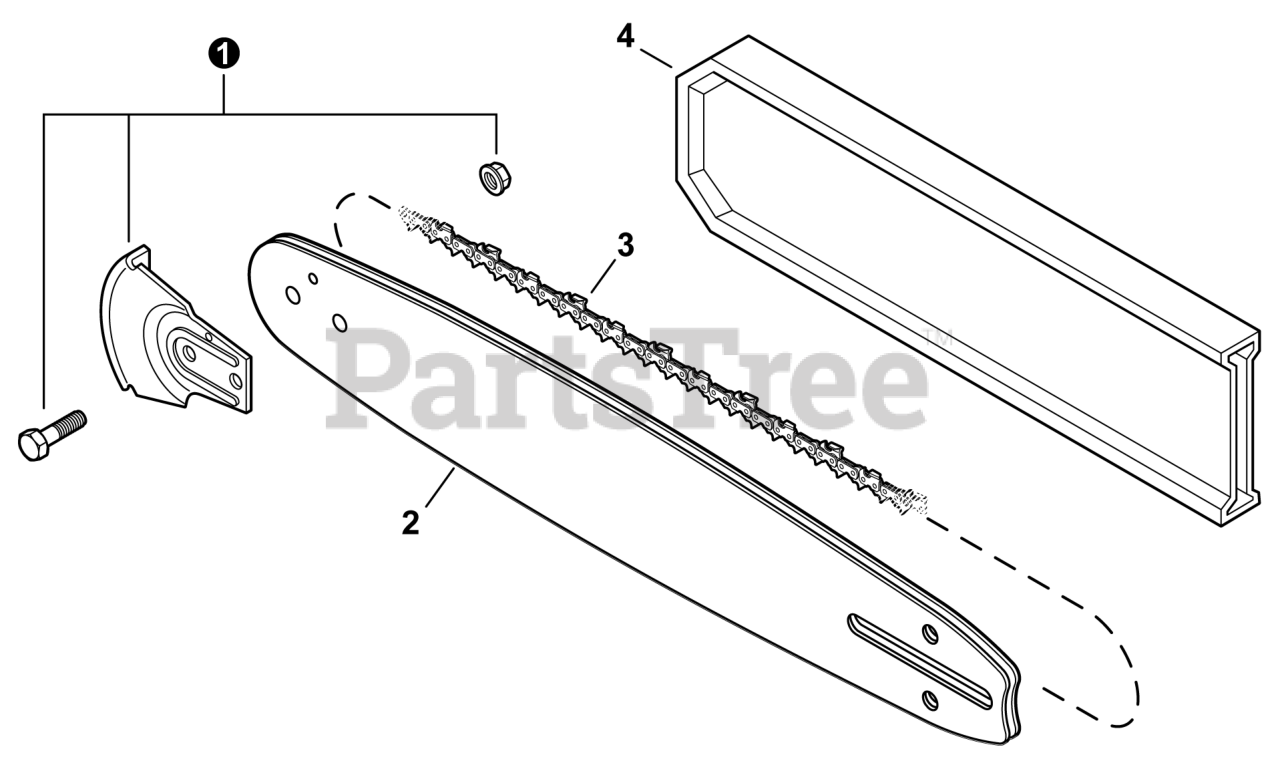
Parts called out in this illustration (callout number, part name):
1	KICK GUARD KIT
2	GUIDE BAR, 12"
2	GUIDE BAR, 14"
2	GUIDE BAR, 16"
3	SAW CHAIN 12"
3	SAW CHAIN 14"
3	SAW CHAIN 16"
4	SCABBARD 12"
4	SCABBARD 14"
4	SCABBARD 16"
